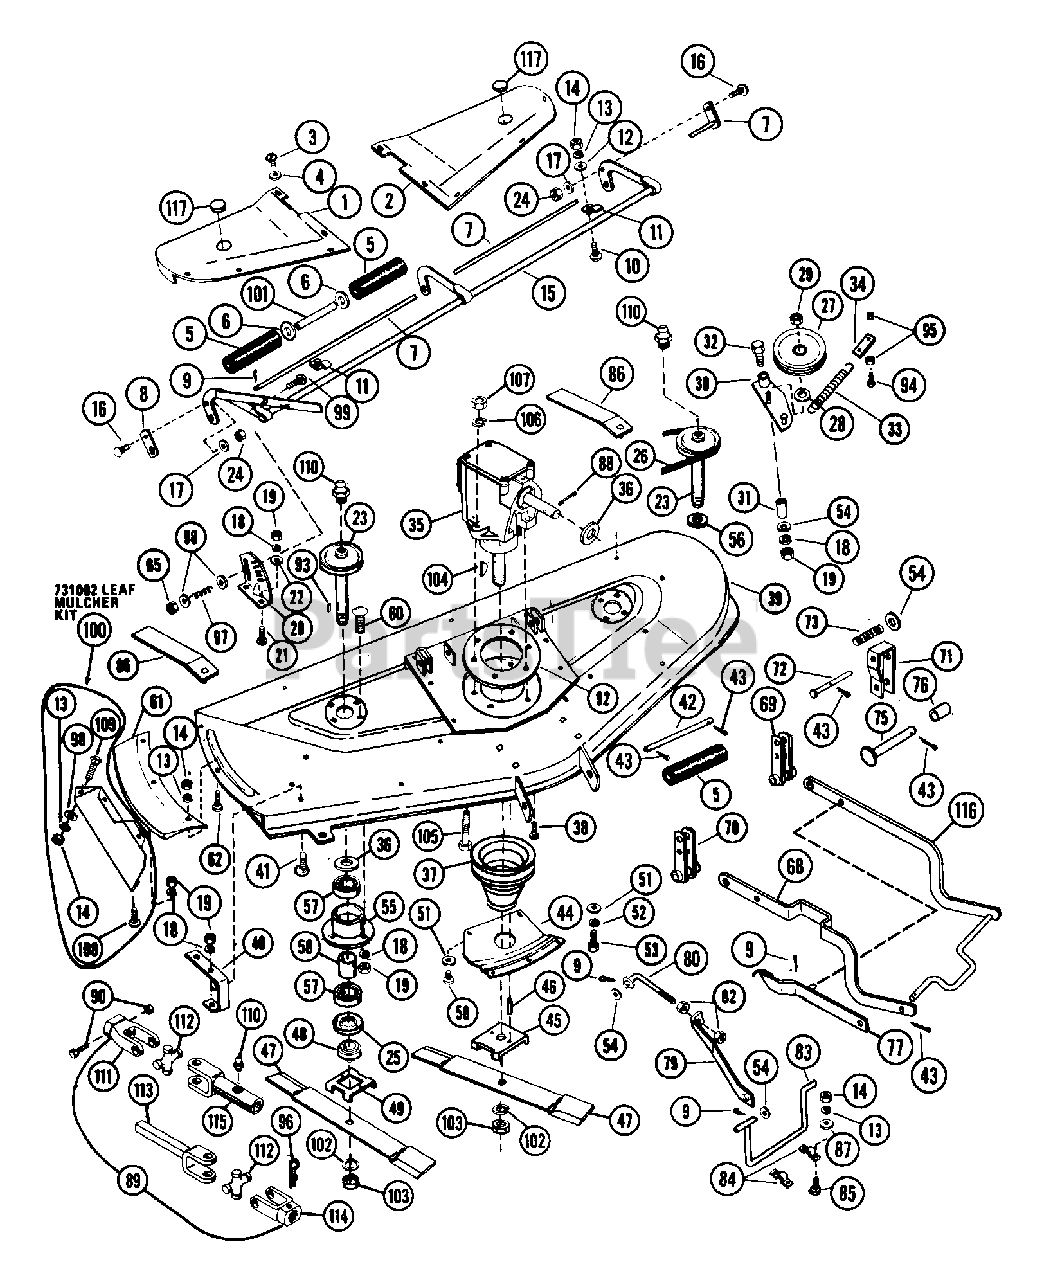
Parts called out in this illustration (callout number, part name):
1	R.H. SHIELD
2	SHIELD ASSEMBLY
3	SCR-TAP .250-20X.50 HH F
4	WSHR-FL-STL.281X.62X.065 PL
6	WSHR-FL-STL .688X1.75X.134PL
7	ROLLER SHAFT
9	PIN-COTR .18X1.0 PL
10	BLT-RDHDSQNK .31-18X1.00 PL
12	WSHR-FL-STL.344X.688X.065PL
13	WSHR-LK .312X.097 PL HVY
14	NUT-HEX .312-18
15	ROLLER ADJUSTMENT
16	BLT-RDHDSQSHNK .38-16X1.00 PL
17	WSHR-FL-STL .438X1.0X.083 PL
18	WSHR-LK .375X.094 MED PL
19	NUT-HEX .375-16
20	HEIGHT QUADRANT
21	BLT-RDHDSQNK .38-16X1.0 PL
22	WSHR-FL-STL.406X.812X.065PL
23	SPINDLE SHEAVE
24	NUT-LK-JAM-CTR .375-16 PL
25	BEARING SLINGER
26	V-BELT, HA-WRAPPED
27	IDLER-FLAT 4.25 X .50 SAL&CLK
28	WSHR-FL-STL .531X.938X.104 PL
29	NUT-LK-CTR .50-13
30	IDLER ARM
31	SPACER .394X.500X1.710
32	BLT-HEX .38-16X2.50 PL GR2
33	SG-TENS .105X.812X3.88 WLD 15
35	MOWER GEAR CASE 48 IN
36	WSHR-FL-STL .754X1.000X.032
38	SCR-TAP .312-18X1.0 THH PL TR
39	48 IN MOWER PAN ASSY
40	R.H. SKID
41	BLT-RDHDSQNK .38-16X.75 SHT PL
43	PIN-COTR .12X1.0 PL
45	BLADE TRAY
46	PIN-GRV .188X.75 TP A
48	RETAINER HUB
49	BLADE TRAY
50	SCR-TAP .250-20X.50 HH F
51	WSHR-FL-STL.281X.62X.065 PL
52	WSHR-LK .250X.077 HVY PL
53	BLT-HEX .25-20X.50 PL GR2
54	WSHR-FL-STL .531X1.062X.095 PL
55	SPINDLE HOUSING
56	WSHR-FL-STL .755X1.375X.062 PL
57	BRG-BALL .750X1.781X.61
58	SPACER .765X1.000X1.180
60	BLT-RDHDSQNK .375-16X.75 PL
61	CHUTE EXTENSION
62	SCR-MCH .31-18X.62 SLTR PL
65	NUT-LK .312-18 GR A PL
68	MOWER HANGER
68	HANGER ARM
71	SUPPORT CHANNEL
72	PIN-CLEV .498X4.50 YWZC
73	SG-COMP .62X.68X1.75
75	PIN-CLEV .498X4.31 YWZC
76	SPACER .516X.749X.938
80	ADJUSTING ROD
82	NUT .50-13 PL
83	SUPPORT SHAFT
85	BLT-RDHDSQNK .31-18X.75 GR5 PL
86	RAMP
87	WSHR-FL-STL.344X.688X.065PL
88	PIN-ROLL .125X1.00
89	PTO SHAFT ASSEMBLY
89	PTO ASSEMBLY
90	SHEARBOLT & NUT ASSEMBLY
92	SHIM
93	KEY-WDRF .188X.625X.25 SAE 61
94	BLT-HEX .38-16X1.00 PL
95	NUT-JAM .375-16 PL
96	PIN-HAIR INT .18X1.18X3.25 PL
97	SG-COMP .063X.53X1.187
98	WSHR-FL-STL .38X.875X.083 PL
99	BLT-RDHDSQNK .31-18X1.75 PL
100	LEAF MULCHER 48 IN - GT
101	SPACER .726X.875X6.375
102	WSHR-LK .750X.188 MED PL
103	NUT-JAM .75-10 PL
104	KEY-WDRF .25X.750X.313 SAE91
105	BLT-HEX .31-18X1.25 PL GR5
107	NUT-LK-TOP .312-18 GR C PL
108	BLT-RDHDSQNK .38-16X1.0 PL
109	BLT-RDHDSQNK .312-18X.62SHTPL
110	SPIN DRIVE ZERK FITTING
112	JOURNAL CROSS & BEARING ASSEMB
113	YOKE AND SHAFT
115	SLIP YOKE
116	MOWER HANGER
117	BUTTON PLUG 1.0
